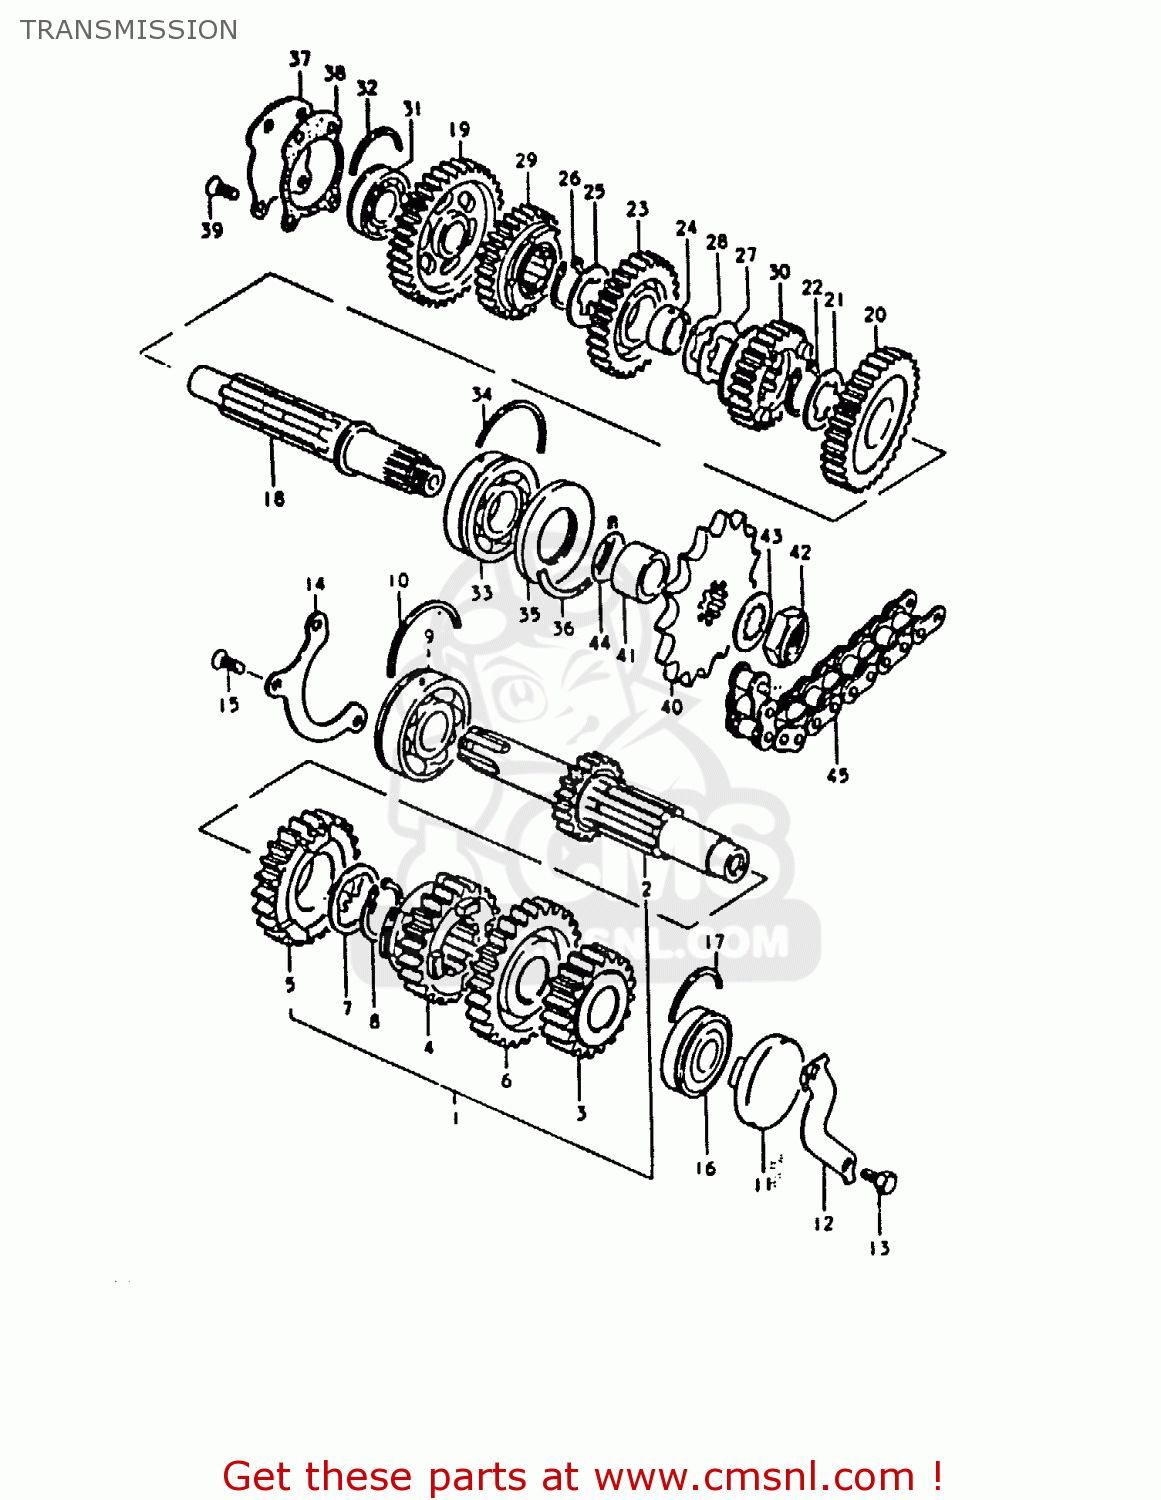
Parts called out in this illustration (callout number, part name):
1	SHAFT ASSEMBLY,COUNTER
2	SHAFT,COUNTER
3	GEAR,SECOND DRIVE
4	GEAR,THIRD DRIVE
5	GEAR,FOURTH DRIVE
6	GEAR,FIFTH DRIVE
7	WASHER,LOCK
8	CIRCLIP
9	BEARING(25X62X17)
10	C-RING
11	PLUG
12	RETAINER,CL PUSH ROD OIL SEAL
13	BOLT
14	RETAINER,CNTR SHAFT BEARING
15	SCREW
16	BEARING(20X47X14)
17	C RING
18	SHAFT,DRIVE
19	GEAR,FIRST DRIVEN
20	GEAR,SECOND DRIVEN
21	WASHER,LOCK
22	CIRCLIP
23	GEAR,THIRD DRIVEN
24	BUSH,3RD DRIVEN GEAR
25	WASHER,LOCK
26	CIRCLIP
27	WASHER,LOCK
28	WASHER
29	GEAR,FOURTH DRIVEN
30	GEAR,FIFTH DRIVEN
31	BEARING
32	C RING
33	BEARING(25X62X17)
34	C-RING
35	SEAL,OIL(32X62X7)
36	C RING
37	PLATE,DRIVE SHAFT
38	GASKET,DRIVESHAFT PLATE (MCA)
39	SCREW
40	SPROCKET,ENGINE
41	SPACER(25X32X18.6)
42	NUT
43	WASHER
44	O RING(D:1,ID:24.5)
45	CHAIN ASSEMBLY,DRIVE
